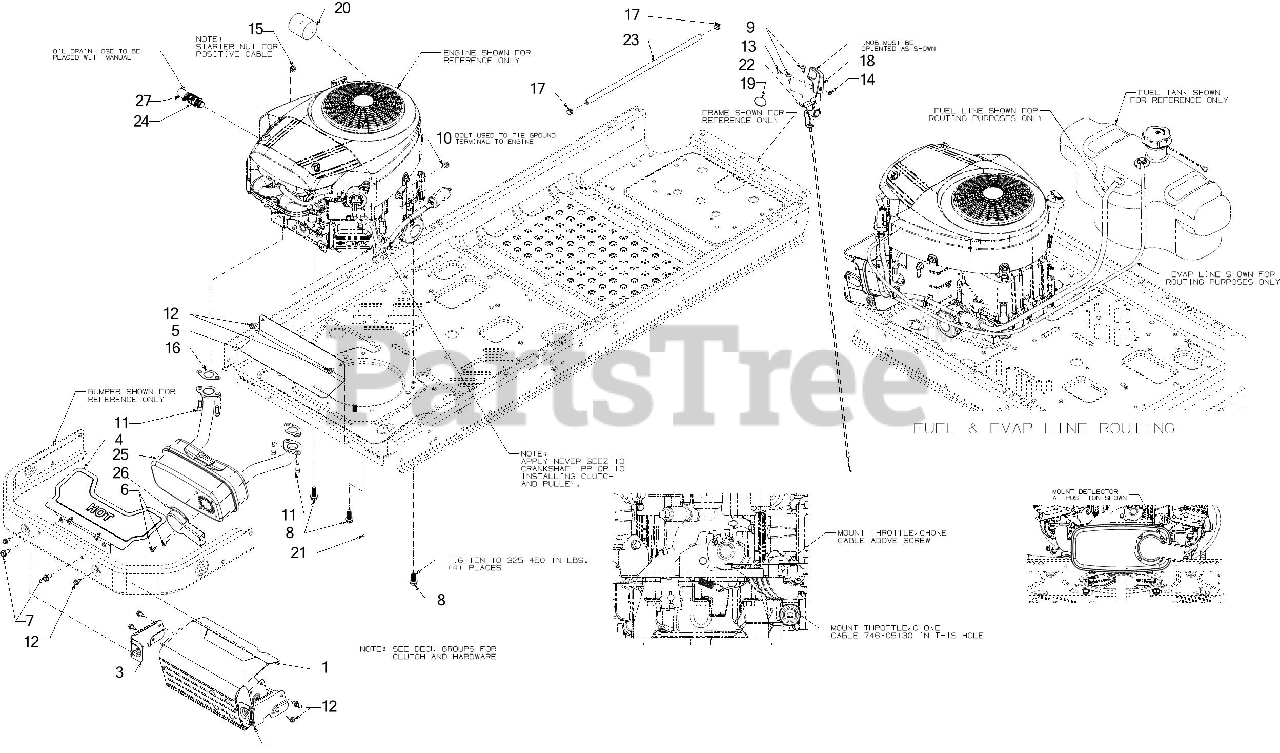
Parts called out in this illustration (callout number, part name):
1	MUFFLER SHIELD W/EXTENSION
2	MUFFLER SHIELD BRACKET (RH)
3	MUFFLER SHIELD BRACKET (LH)
4	MUFFLER HEAT SHIELD
5	LOWER HEAT SHIELD
6	HEX SCREW WASHER HD #8-18 x 0.500
7	SCREW 5/16-18 x .750
8	SCREW 3/8-16 x 1
9	SCREW 1/4-20 x .5
10	SCREW 1/4-20 X.500
11	SCREW 5/16-18 x .625
12	SCREW 1/4-20X.625
13	SCREW #8-32X.38 LG
14	HEX NUT 8-32
15	FLANGE LOCK NUT
16	MUFFLER GASKET
17	HOSE CLAMP 1/20
18	THROTTLE CONTROL KNOB
19	CHOKE PLUG
20	SAE OIL 10W30 (Not Serviceable)
21	ANTI-SIEZE GREASE (Not Serviceable)
22	THROTTLE CABLE 38"
23	FUEL HOSE LOW PERMEATION
24	OIL DRAIN VALVE
25	EXHAUST MUFFLER(B&S)(TWIN)
26	EXHAUST DELECTOR
27	DRAIN HOSE 14''
